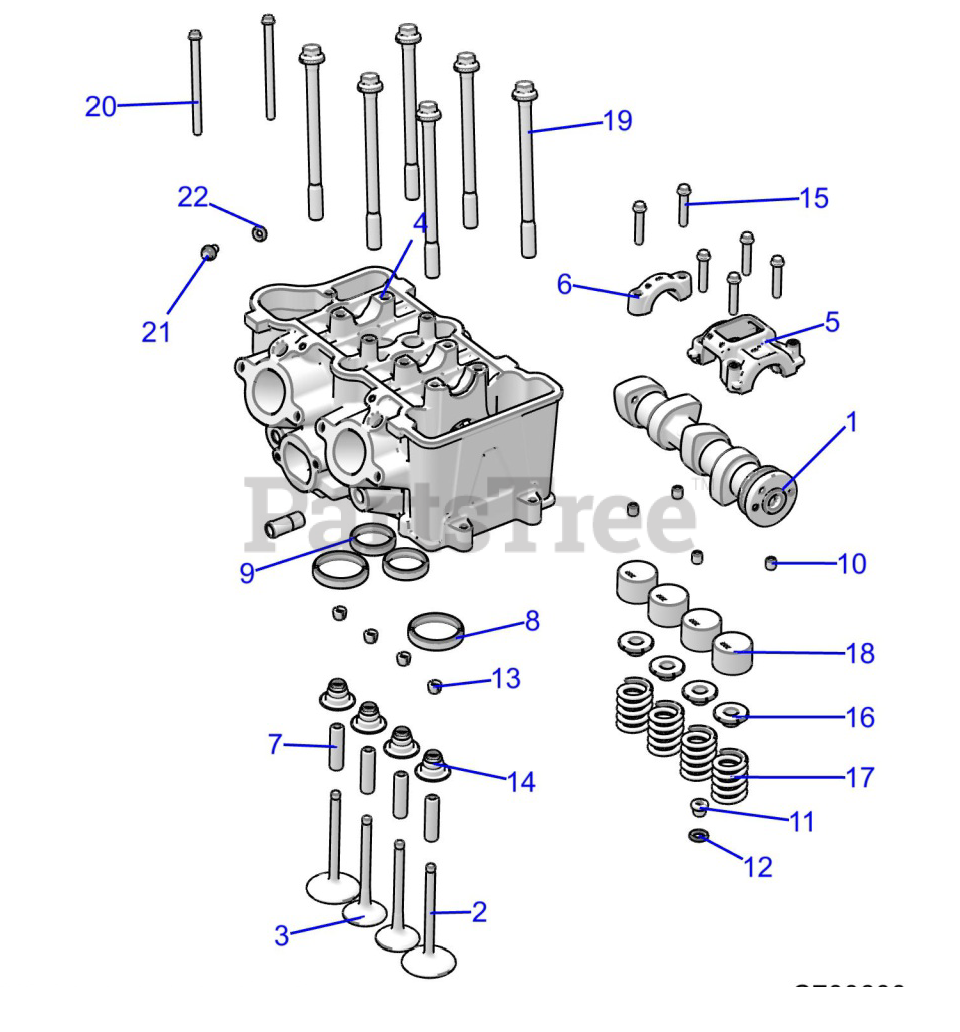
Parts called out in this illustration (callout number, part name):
2	VALVE-INTAKE,47MM
3	VALVE-EXHAUST,38MM
4	ASM-HEAD,MACH,SOHC
10	DWL-HOL,M8X8
11	PLUG-M10X1.0
12	WSHR-10.3X16X1.5 CU
13	KEEPER-VALVE
14	SEAL-VALVE STEM,SPRING SEAT
15	SCR-HXFL-M6X1.0X35 10.9 ZY3
16	RETAINER-VALVE SPRING
17	SPRING-VALVE
19	BOLT-HEAD,M11X1.25X150,SEMS
21	SCR-M6X1.0X13,SL/HX/FL-Z,BLEED
22	WASHER-FLAT,6.15X12X1MM-AL
